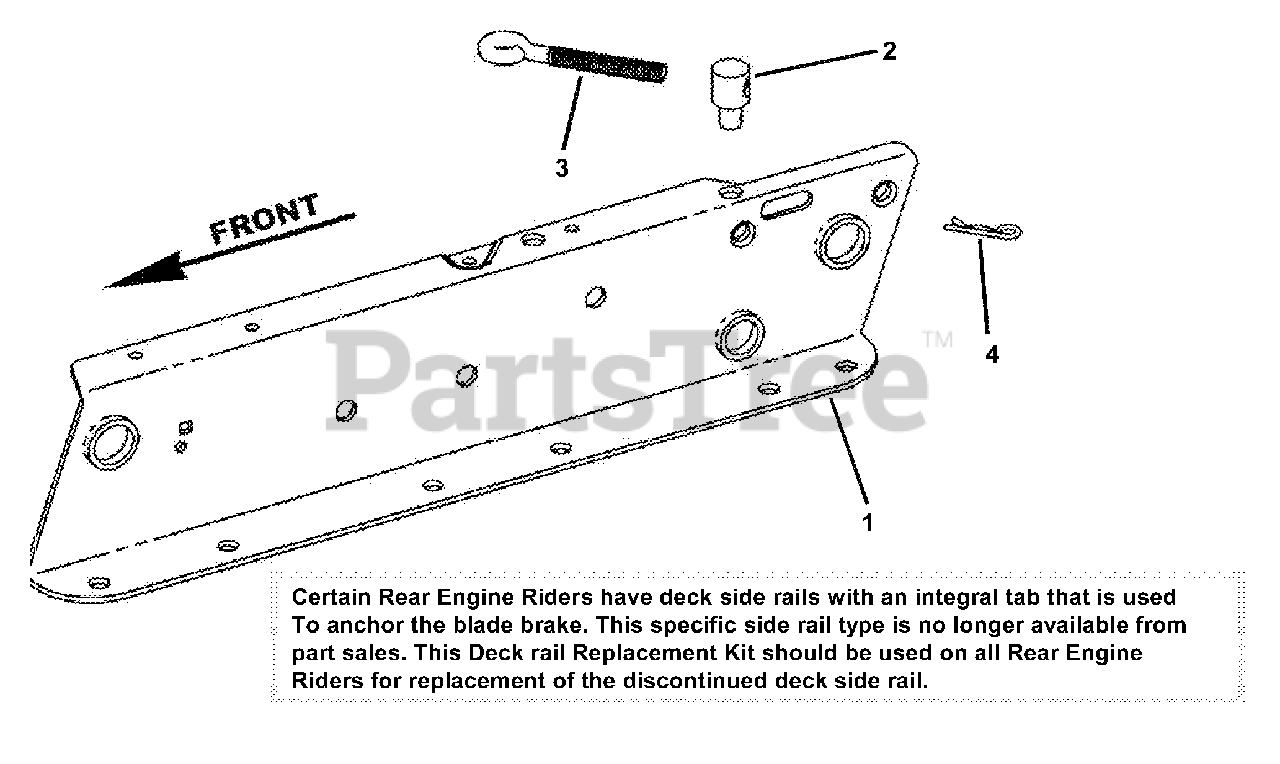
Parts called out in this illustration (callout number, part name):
1	RAIL, Deck Lift Left Hand
2	SWIVEL
3	EYE BOLT
4	HAIR PIN
